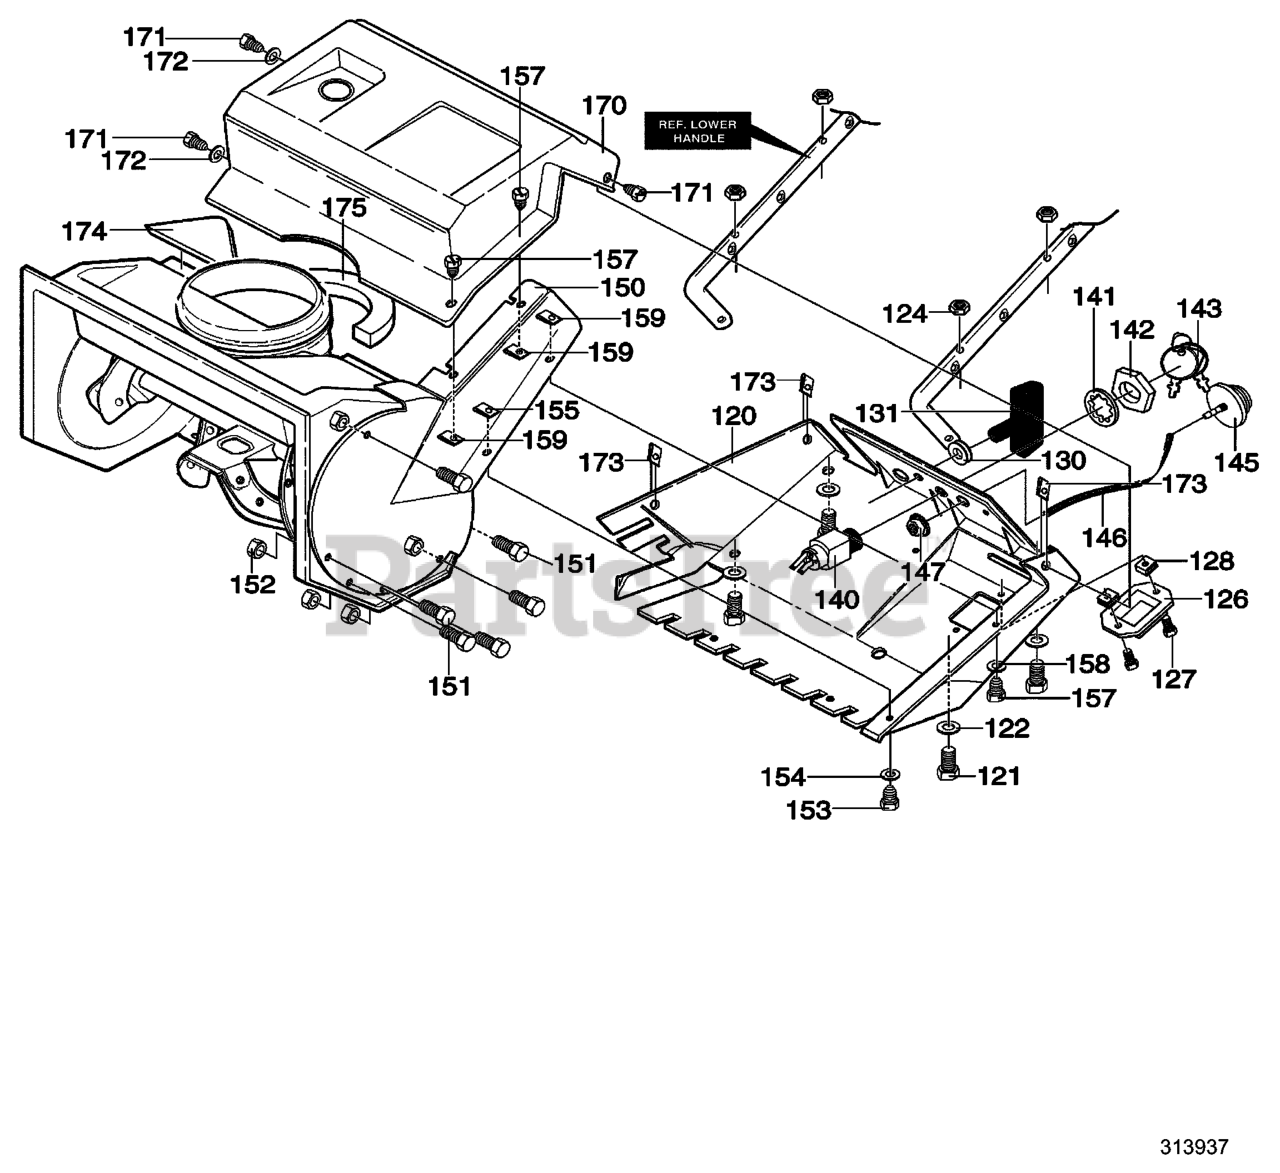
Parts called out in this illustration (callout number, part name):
120	COVER, BOTTOM
121	SCREW, 1/4-20X1.25
122	WASHER, FLAT .281X.63X.065
124	NUT, 1/4-20 YZ
126	COVER, CARB
127	SCREW, 1/4-14X.75
128	NUT, 1/4-10 SPEED J TYPE
130	GROMMET & WASHER, ROPE GUIDE
131	KNOB, STAND TEE
140	SWITCH, IGNITION
141	WASHER
142	NUT, 5/8-32 ACC
143	2 KEYS & RING
145	PRIMER, ENGINE
146	HOSE, PRIMER
147	KEPS NUT, 1/4-20
150	COVER, BELT
151	SCREW, 10-24X.50
152	NUT, #10-24
153	SCREW, 1/4-20X.50
154	WASHER, FLAT .281X.63X.065
155	NUT, 1/4-20 TINN
157	SCREW, 1/4-14X.75
158	WASHER, FLAT .281X.63X.065
159	NUT, 1/4-20 SPEED J TYPE
170	COVER, TOP
171	SCREW, 1/4-14X.75
172	WASHER, FLAT .281X.63X.065
173	NUT, 1/4-10 SPEED J TYPE
174	SEAL, FOAM
175	SEAL, STRIP CHUTE & GAS SEAL
